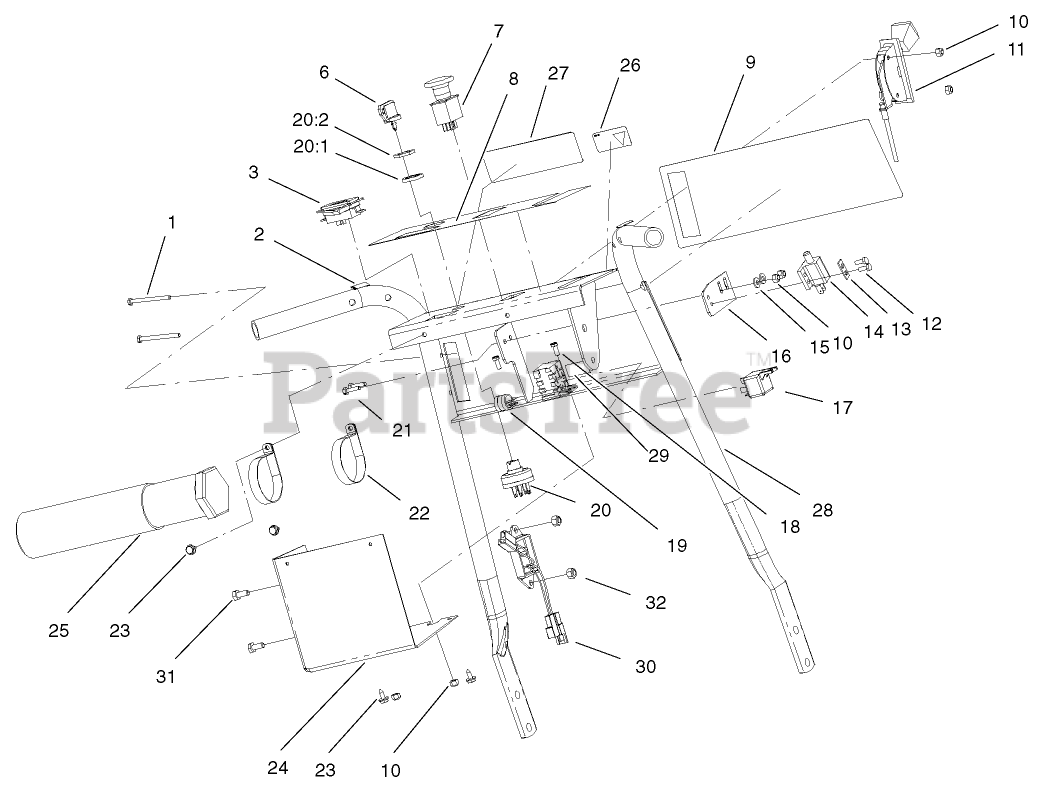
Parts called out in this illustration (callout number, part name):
1	SCREW-SHH
2	DECAL-LOCK, NEUTRAL
3	HOURMETER
6	KEY-IGNITION
7	SWITCH-PTO
8	Decal-Warning
9	DECAL-PROLINE
10	NUT-LOCK, NI
11	CONTROL-THROTTLE
12	SCREW-TAPTITE
13	PLATE-SWITCH
14	SWITCH-POLE, SINGLE
15	WASHER-FLAT
16	PLATE-MOUNTING, SWITCH
18	SCREW-HWH
19	CLAMP-R
20	SWITCH-ON / OFF
20:1	NUT-HH
20:2	WASHER-TOOTH, INTERNAL
21	SCREW-HWH
22	CLAMP-R
23	SCREW-HWHTF
24	BRACKET-COVER
25	TUBE-MANUAL
26	DECAL-PROTECTION, EAR
27	DECAL-WARNING
28	Handle ASM
29	DECAL-RELAY, 24 VOLT
30	Module-Filter
31	SCREW-HH
32	NUT-LOCK, NI
